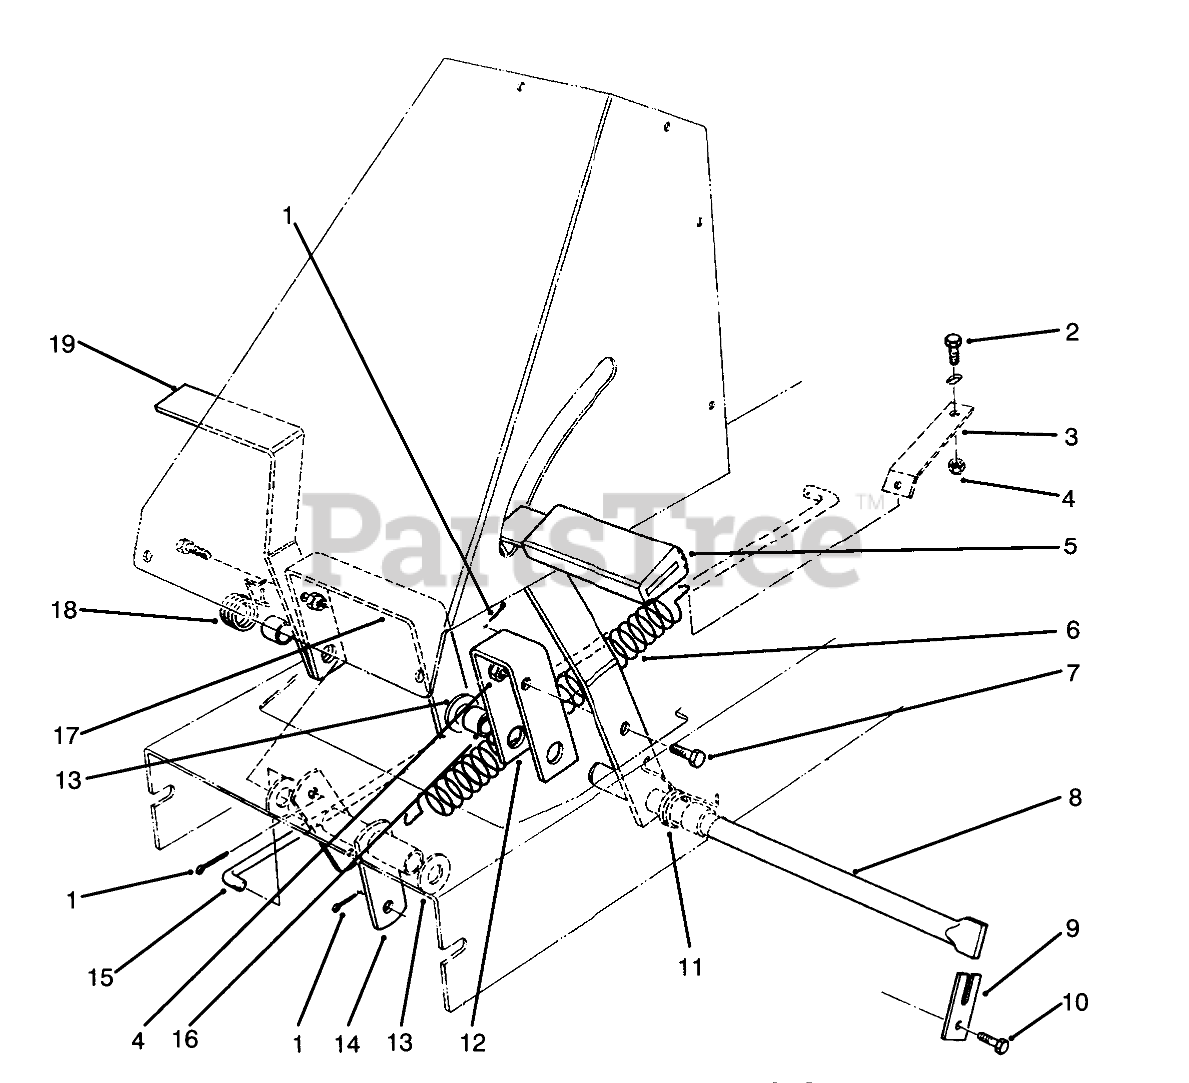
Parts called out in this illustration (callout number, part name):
1	PIN-COTTER
2	SCREW-HH
3	BRKT-SPRING RET
4	NUT-LOCK, NI
5	PAD-PEDAL
6	SPRING-EXTENSION
7	SCREW-HH
8	SHAFT-PEDAL PIVOT
9	RETAINER-SHAFT
10	SCREW-HH
11	SPRING-TORS CLUTCH
12	Bracket-Clutch Pedal
13	WASHER-FLAT
14	Pivot Tube
15	ROD-ENGAGE
16	SPACER-PEDAL
17	Bracket-Brake Pedal
18	SPRING-TORS BRAKE
19	Pedal
